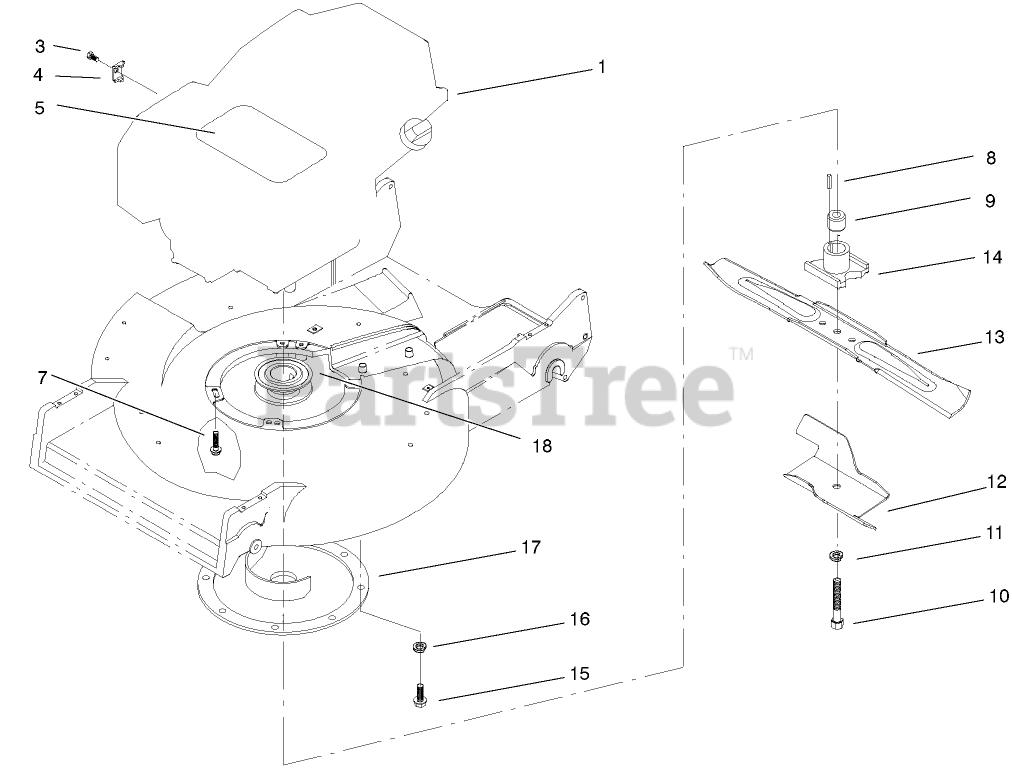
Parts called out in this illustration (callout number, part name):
3	BOLT (5X18)
4	CLAMP
5	DECAL-ENGINE
7	SCREW-MOUNT, ENGINE
8	KEY-SQUARE
9	SPACER-BLADE RETAINER
10	SCREW-BLADE
11	WASHER-LOCK
12	STIFFENER-BLADE
15	SCREW-HWHTF
16	WASHER-LOCK, INTERNAL
18	PULLEY-DRIVER
